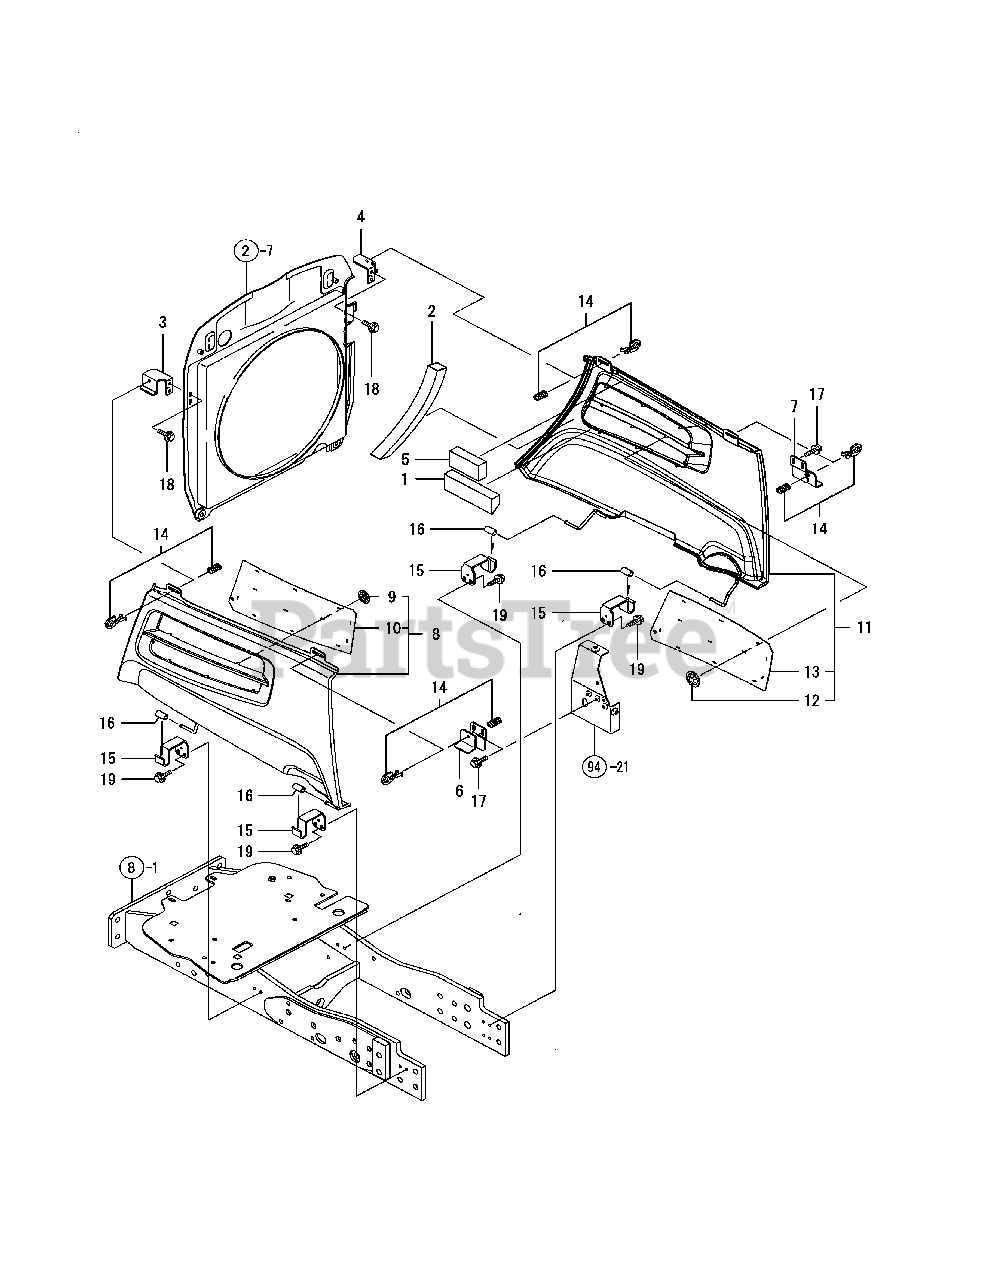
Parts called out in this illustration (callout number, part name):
1	URETHANE, A COVER
2	URETHANE, B COVER
3	BRACKET, L
4	BRACKET, R
5	URETHANE, C COVER
6	BRACKET, L.H. COVER
7	BRACKET, R.H. COVER
8	COVER (M ASSY SIDE L)
10	NET, L SIDE COVER
11	COVER (M ASSY,SIDE R)
13	NET, R SIDE COVER
14	LOCK COMP.,CAM
15	STAY, SIDE COVER
16	RUBBER, CUSHION
17	BOLT M 6X 12 PLATED
18	BOLT M 6X 12 PLATED
19	BOLT M 8X 12 PLATED
